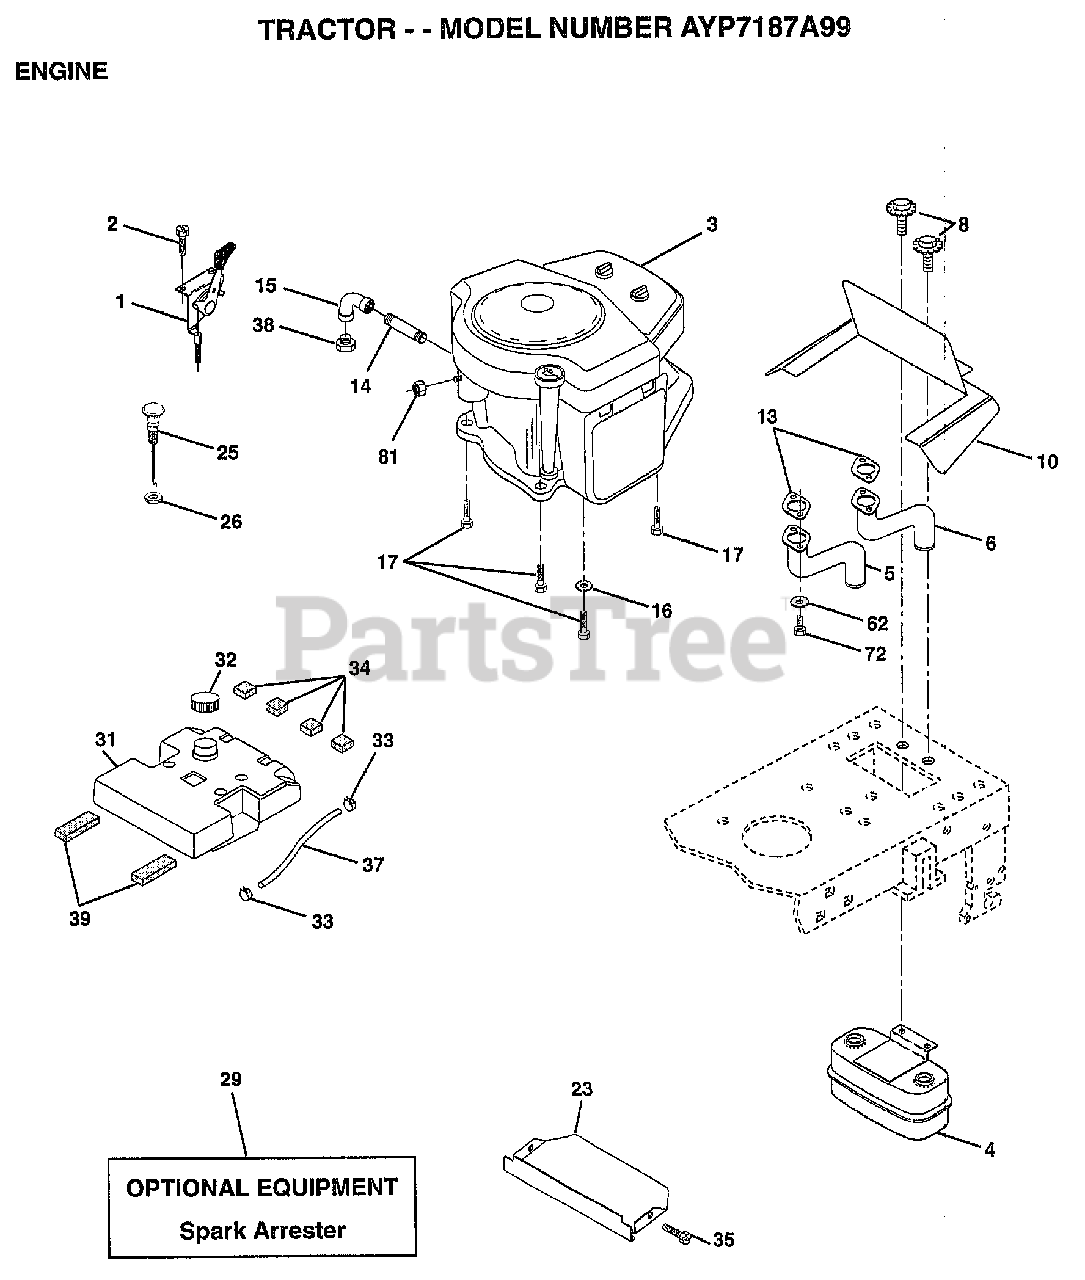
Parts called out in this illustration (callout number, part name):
1	CONTROL THROT. LH
2	SCREW LT
4	MUFFLER.TW.LOTONE
5	TUBE MANIFOLD LH
6	TUBE MANIFOLD RH
7	CLAMP.TUBE.DBL.EN
8	BOLT.5/16-18.UNC
10	SHIELD.BROWNING
13	GASKET MUFFLER
14	PIPE NIPPLE LT
15	ELBOW
16	LOCKWASHER
17	SCREW LT
23	SHIELD.BRN/DBR.GD
25	CONTROL.CHOKE.37
26	"NUT,KEPS 3/8-24IM"
31	"TANK.FUEL,3.5 GAL"
32	CAP ASM FUEL
33	HOSE CLAMP
34	PAD-SPACER LT
35	SCREW
37	FUEL LINE T
39	PAD IDLER TI
62	LOCKWASHER
72	SCREW
81	NUT
